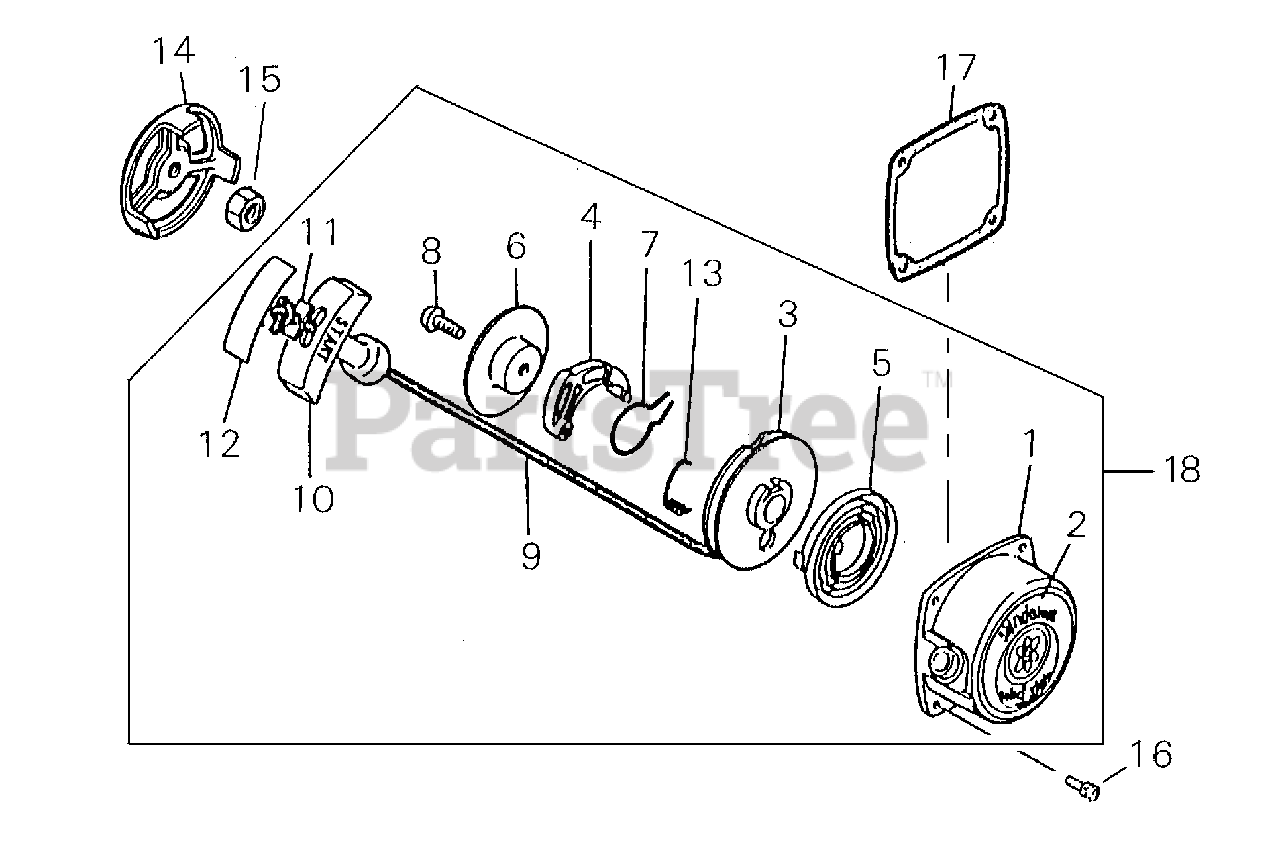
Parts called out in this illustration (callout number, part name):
1	CASE, STARTER
2	NAME PLATE
3	REEL, ROPE
4	PAWL, STARTER
5	SPRING, REWIND
6	PLATE, STARTER
7	SPRING
8	SCREW
9	ROPE
10	GRIP, STARTER
11	RETAINER, ROPE
12	TAPE
13	SPRING, RETURN
14	CATCHER, STARTER
15	NUT - 8
16	SCREW - 4X16
17	GASKET
18	STARTER ASSY
